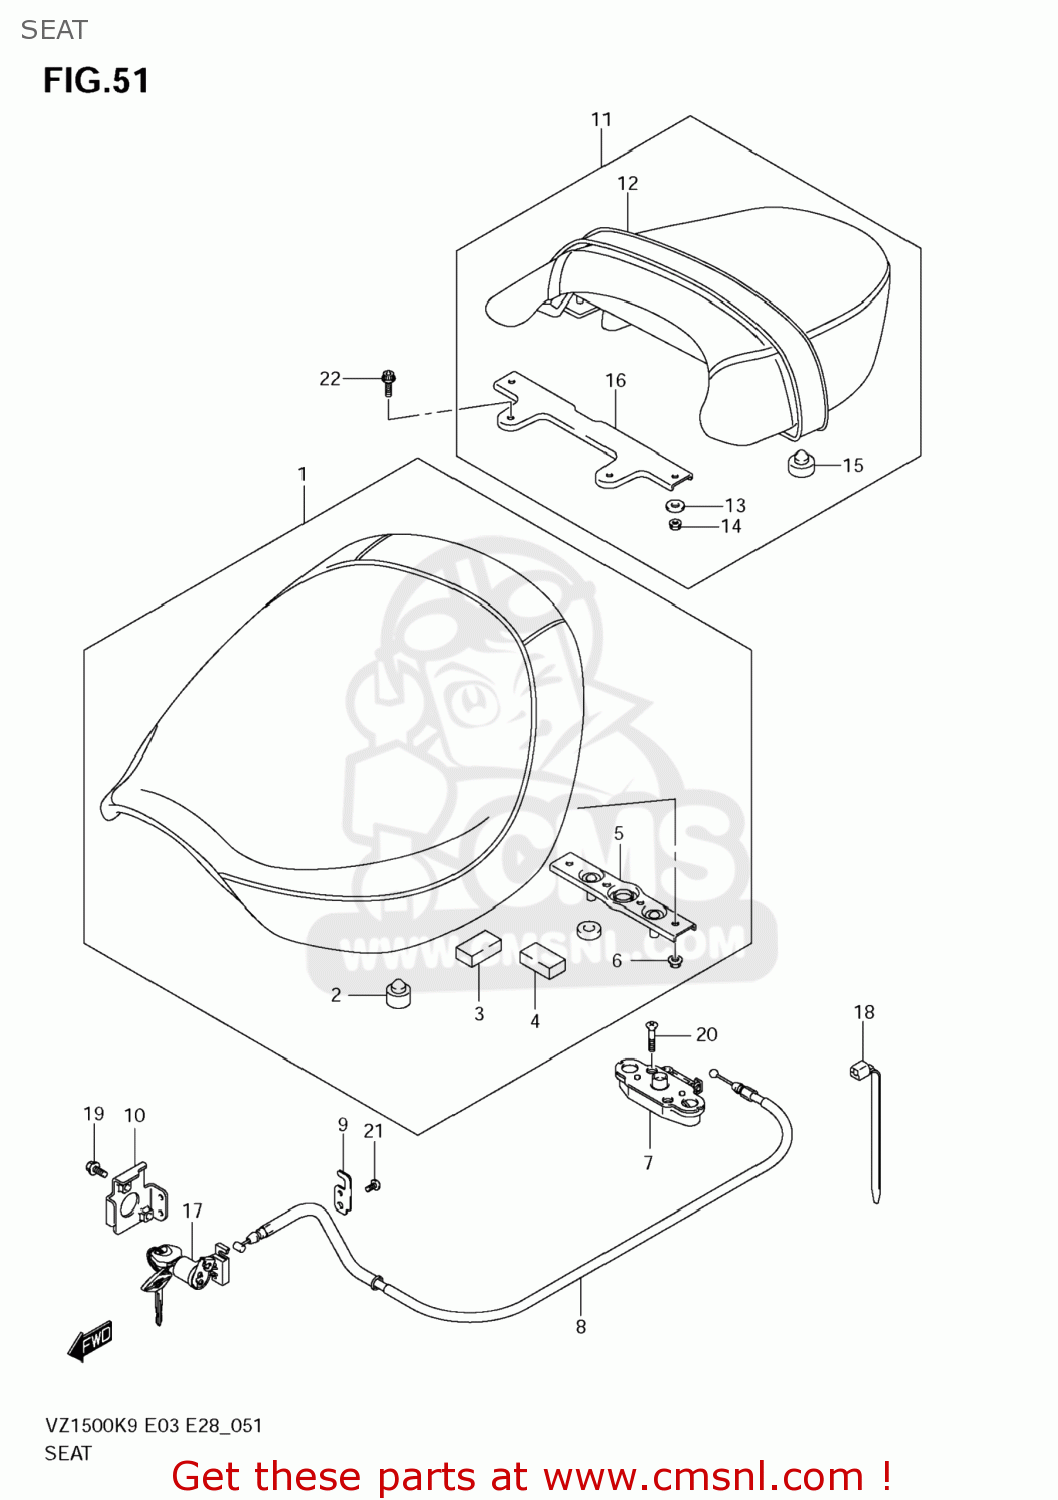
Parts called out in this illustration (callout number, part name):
1	SEAT ASSY
2	CUSHION
3	CUSHION
4	CUSHION
5	STRIKER,SEAT L
6	NUT
7	BRACKET,SEAT SUPPORT,RIGHT
8	CABLE,SEAT LOCK
9	PLATE,SEAT LOCK
10	BRACKET,SEAT LOCK
11	SEAT ASSY,PILLION
12	BAND ASSY(BLACK)
13	WASHER(6.5X20X1.6)
14	NUT
15	CUSHION(11.5X22X20)
16	BRACKET,BAND
17	LOCK SET,SEAT
18	CLAMP(L:190)
19	BOLT
20	SCREW
21	SCREW
22	BOLT
